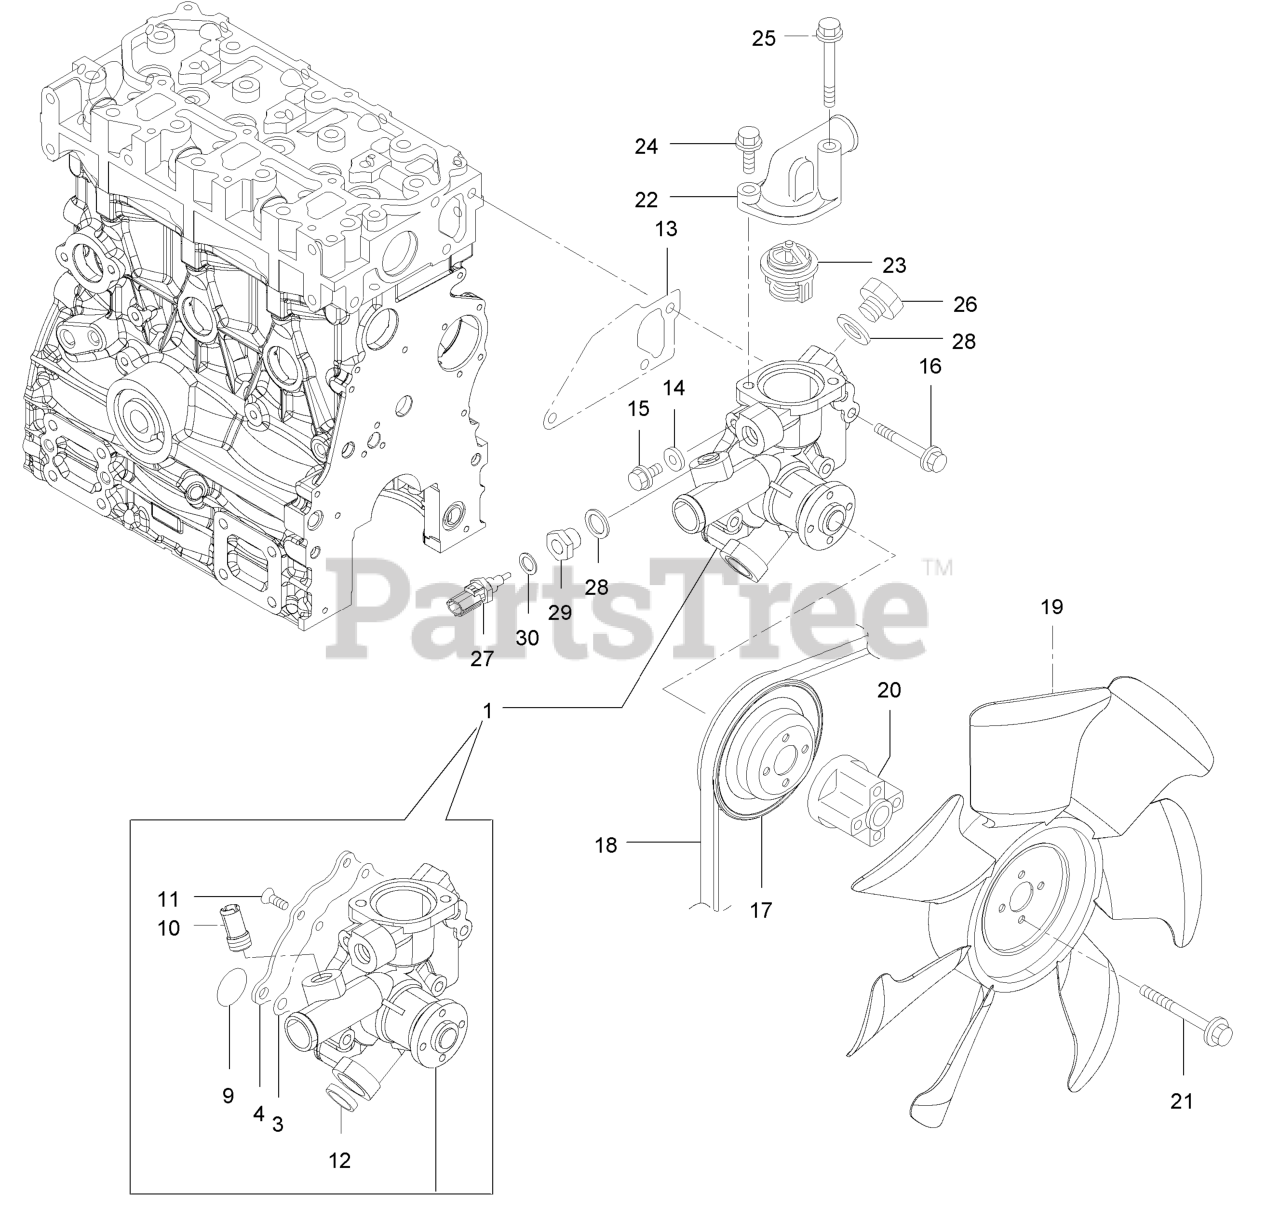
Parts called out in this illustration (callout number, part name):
1	Pump ASM-Water
10	Joint-Pipe
13	Gasket-Water Pump
17	V-Pulley
19	Fan-Cooling 1
20	Spacer-Fan
22	Cover-Thermostat
23	Thermostat
27	Sensor-Thermostat, CW
30	Washer-Seal
